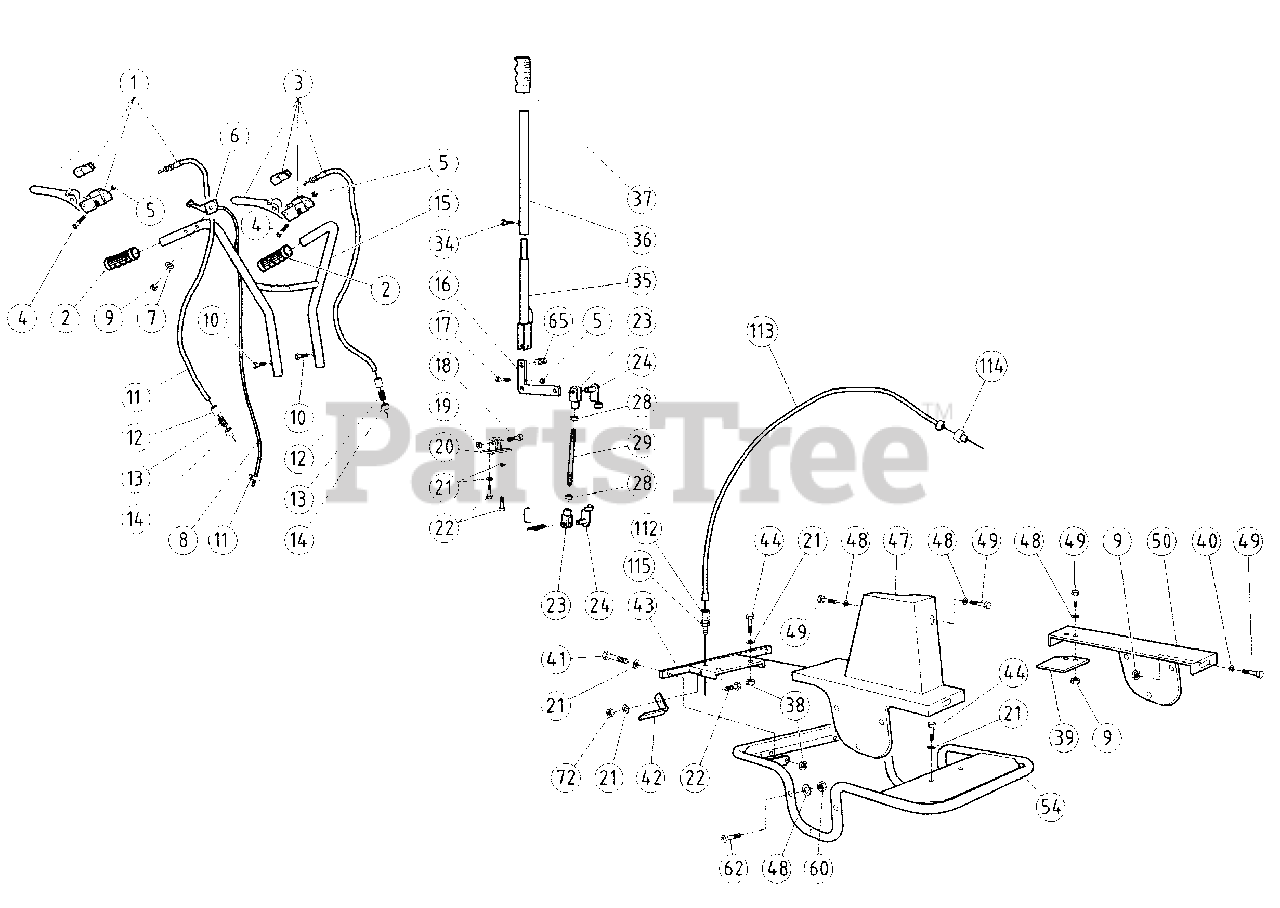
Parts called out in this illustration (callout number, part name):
1	Lever Control (righthand )
3	Lever Tightener (lefthand)
4	Screw M6x55 UNI 5931
5	Nut Lock M6 H6
6	Lever Hand Accelerator
7	Washer Flat M6
8	Cable Accelerator
9	Nut Lock M6 H8
10	Screwcap M10x 20
11	Clamp Accelerator
12	Spring guide
13	Spring 10x25 C X F
14	Cable guide
17	Screwcap M6x45 P.F.
18	Screwcap M10x50 P.F.
19	Nut Lock M10
20	Support Lever Height adjustment
21	Washer Flat M8
22	Screwcap M8x16
23	Fork 03216055
24	Clip Fork
29	Rod Tie Height-adjustment
34	Screwcap M8x16
35	Lever Height adjustment
36	Extension Height Adjustment Lever
37	Knob 0 22
38	Nut Lock M8
39	Plate Stopping Reverse Gear
40	Washer Flat M6x18
41	Screwcap M8x25
42	Bracket Rear
43	Support Rear guard
44	Screwcap M8x20
47	Guard Belt
48	Washer Flat M6
49	Screwcap M6 x 14
50	Guard Side (lefthand)
54	Guard Support Frame
60	Nut Lock MS H6.5
62	Screw Crosshead MSx30
65	Spring 13x25
72	Nut 8 H 6.5
112	Adjuster M6 X 40
113	Cable Control Brake
114	Bushing Sheath
115	Nut M6 H4
